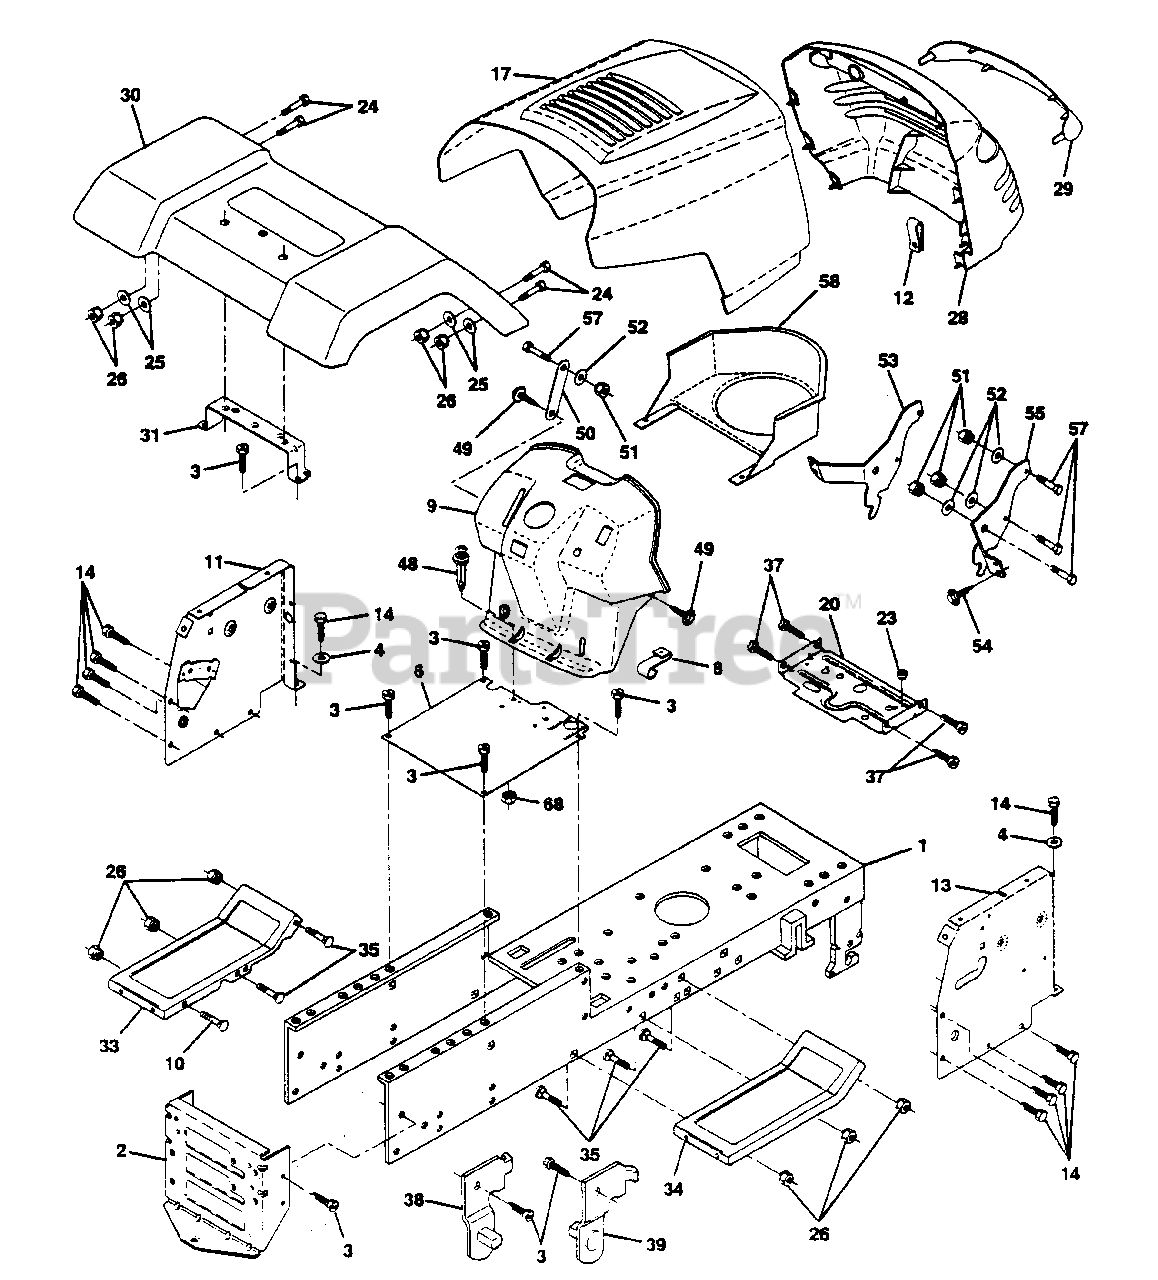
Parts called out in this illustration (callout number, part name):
1	Chassis Weldment 11ga (AYP part number)
2	Drawbar, Stretch (AYP part number)
3	Screw Thdrol 3/8-16x3/4 Ty-tt (AYP part number)
4	Washer 13/32 x 3/4 x 16 Ga. (AYP part number)
5	Washer Lock Ext. Tooth 3/8 (AYP part number)
6	Saddle LT Fender Shift (AYP part number)
8	Clip Insulator .406 (AYP part number)
9	Dash Private Label (AYP part number)
10	Bolt Carriage 3/8-16 x 1 (AYP part number)
11	Panel Pnt Dash Lh (AYP part number)
12	Clip Tinnerman Grille P/L (AYP part number)
13	Panel Dash Rh Weldment (AYP part number)
14	Screw Thdrol 3/8-16x1/2 Ty-tt (AYP part number)
17	Hood Paint Steel Private Label (AYP part number)
20	Plate Mtg. Battery Fuel Tank 95 (AYP part number)
24	Bolt Fin Hex 3/8-16unc X1 (AYP part number)
25	Washer 13/32 X 13/16 X 12 Ga (AYP part number)
26	Nut Lock 3/8-16 Unc (AYP part number)
28	Grille Private Label (AYP part number)
29	Lens Grille Private Label (AYP part number)
30	Fender Pnt (AYP part number)
31	Bracket Pnt Fender (AYP part number)
33	Footrest Pnt Lh (AYP part number)
34	Footrest Pnt Rh (AYP part number)
35	Bolt Rdhd Sht Sqnk 3/8-16 X3/4 (AYP part number)
37	Screw Thdrol 5/16-18 X 1/2 TYT (AYP part number)
38	Bracket, Asm. Pivot, L.H., Mower Rear (AYP part number)
39	Bracket, Asm. Pivot, R.H., Mower Rear (AYP part number)
48	Rivet Push (AYP part number)
49	Screw Hexwsh. Thdrol 1/4-20 x 3/4 (AYP part number)
50	Brace (AYP part number)
51	Nut Lock Hex W/Ins 1/4-20 (AYP part number)
52	Washer 9/32 x 7/8 x 16 Ga. (AYP part number)
53	Bracket Grille Lh (AYP part number)
54	Screw Lock Spider #8 x 7/8 (AYP part number)
55	Bracket, Grille Rh (AYP part number)
57	Screw Hex 1/4-20 x 3/4 (AYP part number)
58	Air Duct P/L (AYP part number)
68	Nut Keps Hex 1/4-20 unc (AYP part number)
